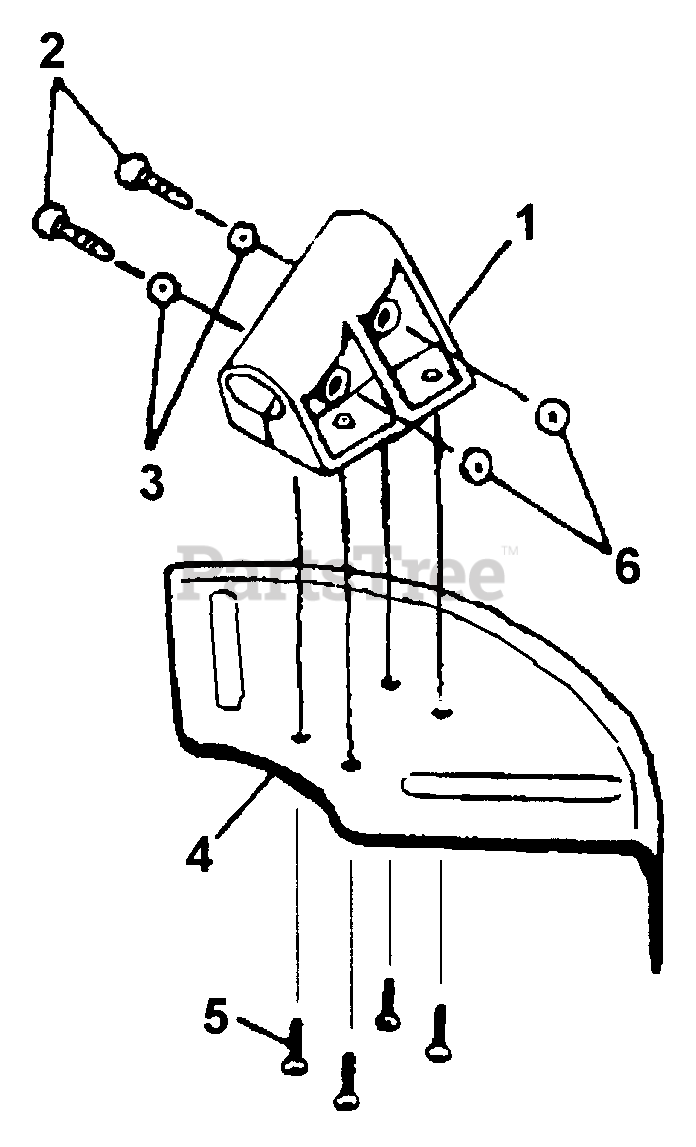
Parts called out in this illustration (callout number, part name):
1	Bracket, Blade Guard
2	Screw
3	Washer
4	Guard
5	Screw
